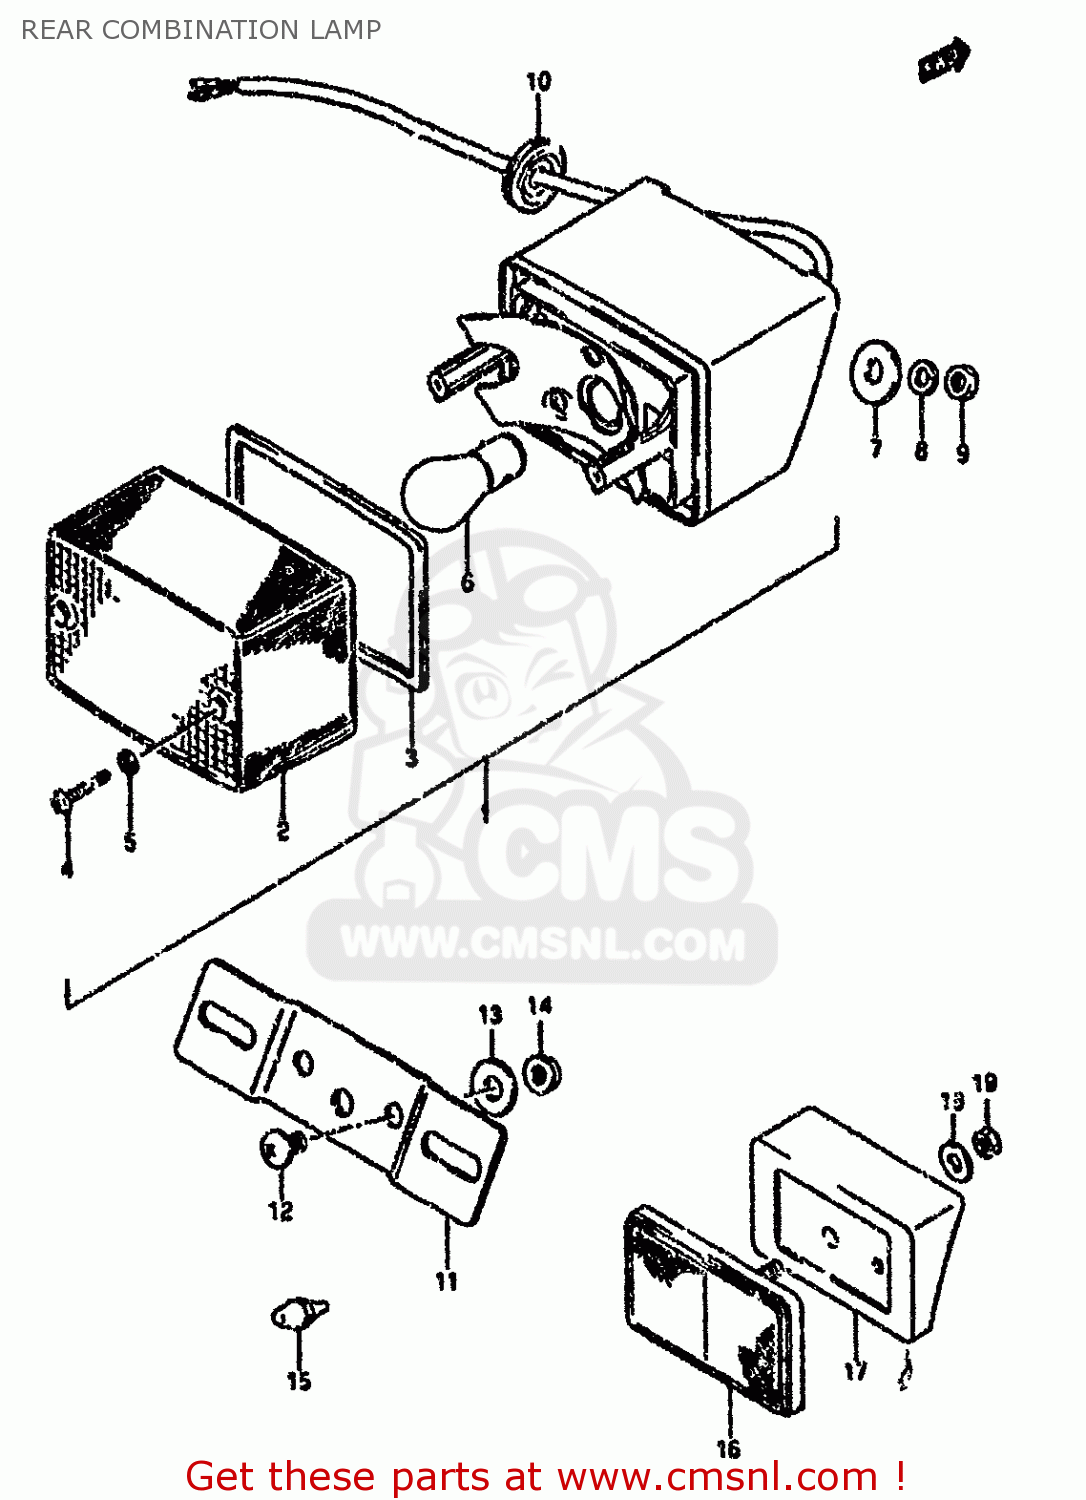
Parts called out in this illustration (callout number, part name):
1	LAMP ASSY,REAR COMBINATION
2	LENS
3	GASKET,RR COMBI LAMP LENS (NAS)
4	SCREW
5	GASKET (NAS)
6	BULB(12V21/5W)
7	WASHER(6,5X22X1.6)
8	LOCK WASHER
9	NUT 6MM
10	GROMMET
11	BRACKET,PLATE LICENSE
12	SCREW 6X12
13	WASHER
14	NUT
15	CUSHION
16	REFLEX REFIECTOR, REAR
17	SPACER
18	WASHER
19	NUT
